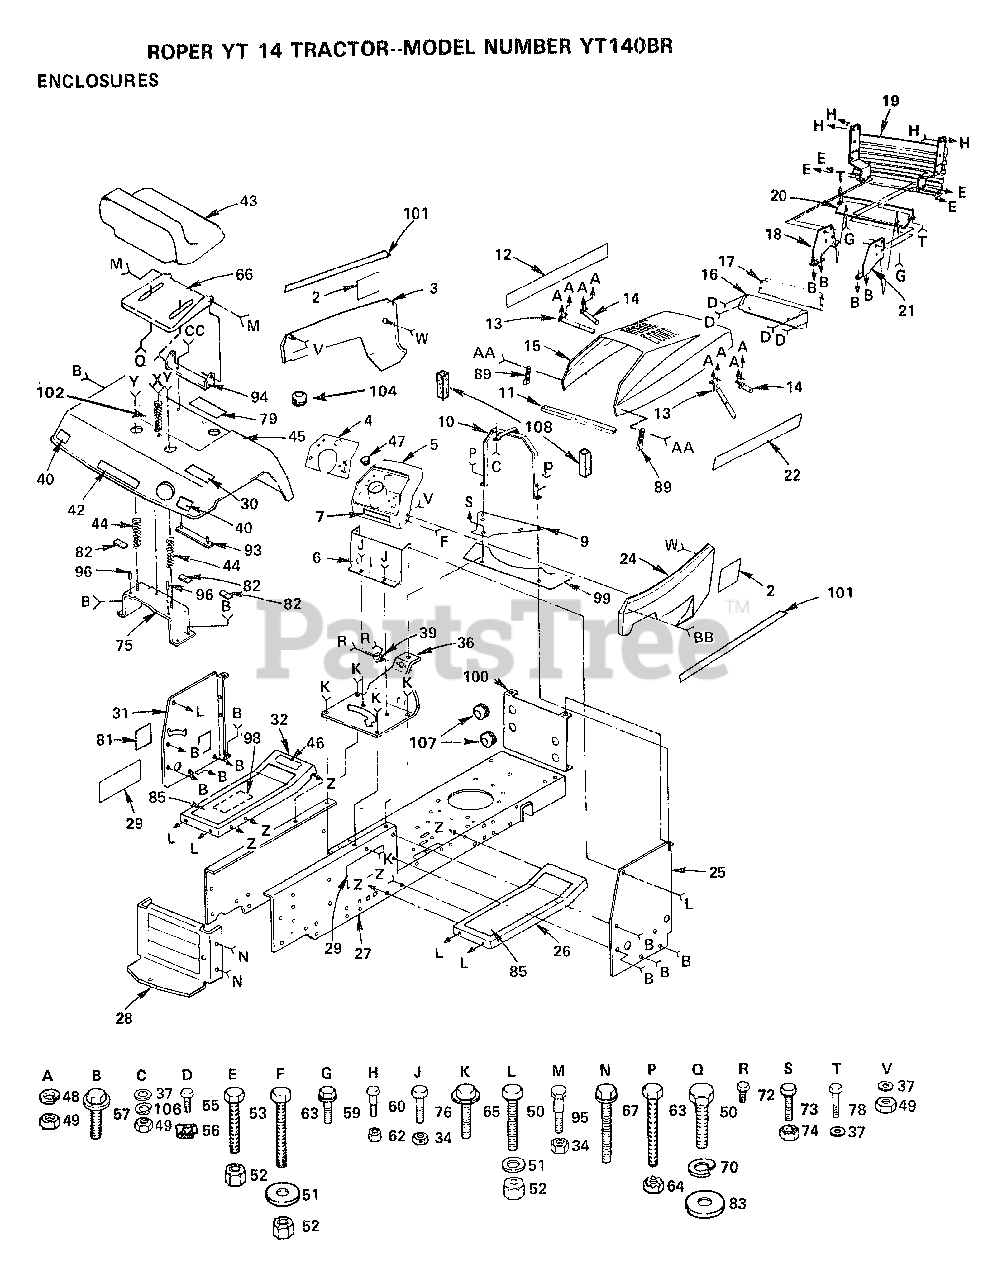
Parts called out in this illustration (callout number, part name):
6	LOWER DASH
17	LENS LT
18	SUPPORT-GRILL LT
30	DECAL-CAUTION
31	PANEL DASH HYT
37	WASHER PM
40	REFLECTOR-TAIL YT
47	PLUG-DASH T
51	WASHER
53	BOLT
54	WASHER
56	"""J"" FASTENER LT"
57	SCREW
59	SCREW
60	BOLT T
64	NUT
65	SCREW LT
66	SEAT PAN T
67	SCREW
70	LOCKWASHER
73	BOLT
78	SCREW HEX CRT
82	"CLAMP, SPRING LT"
83	WASHER T
94	BRKT.ASM.SEAT.P
96	NUT-PUSH YT
102	SPRING T
104	GROMMET T
107	SNAP BUSHING T
108	STRIP - FOAM
